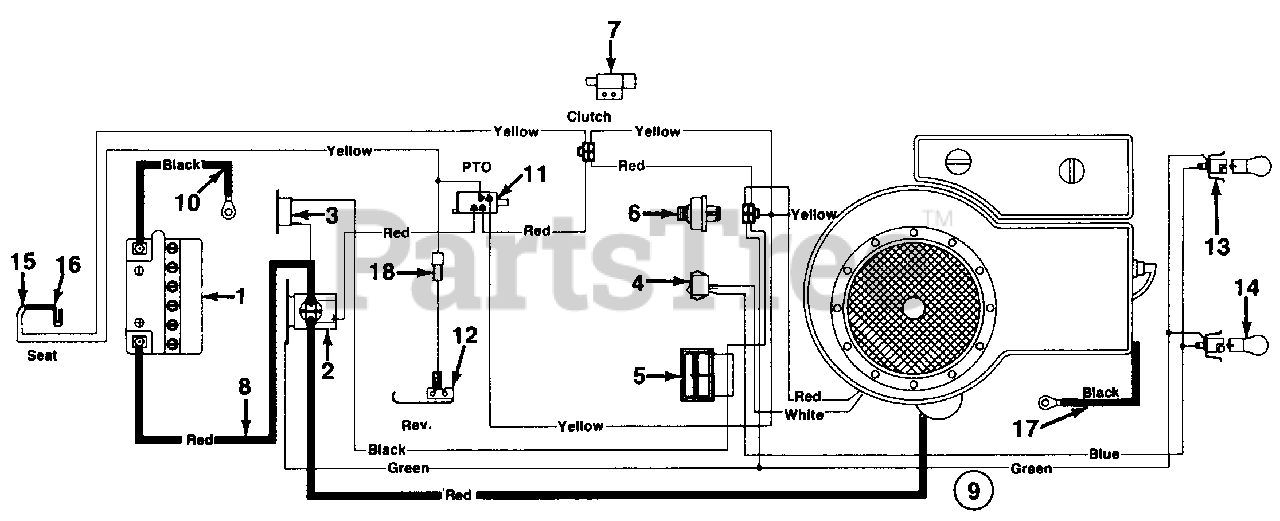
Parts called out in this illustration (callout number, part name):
1	Battery
2	Solenoid
3	Circuit Breaker
4	Light Switch
5	Ammeter
6	Ignition Switch
7	Safety Switch
8	Electric Wire-8" Lg.
9	Wire Harness
10	Ground Wire 11.5" Lg.
11	Safety Switch
12	Safety Switch
13	Socket
14	Bulb
15	Safety-Switch
16	Safety Switch
17	Ground Wire 7.5" Lg.
18	Ext. Wire
